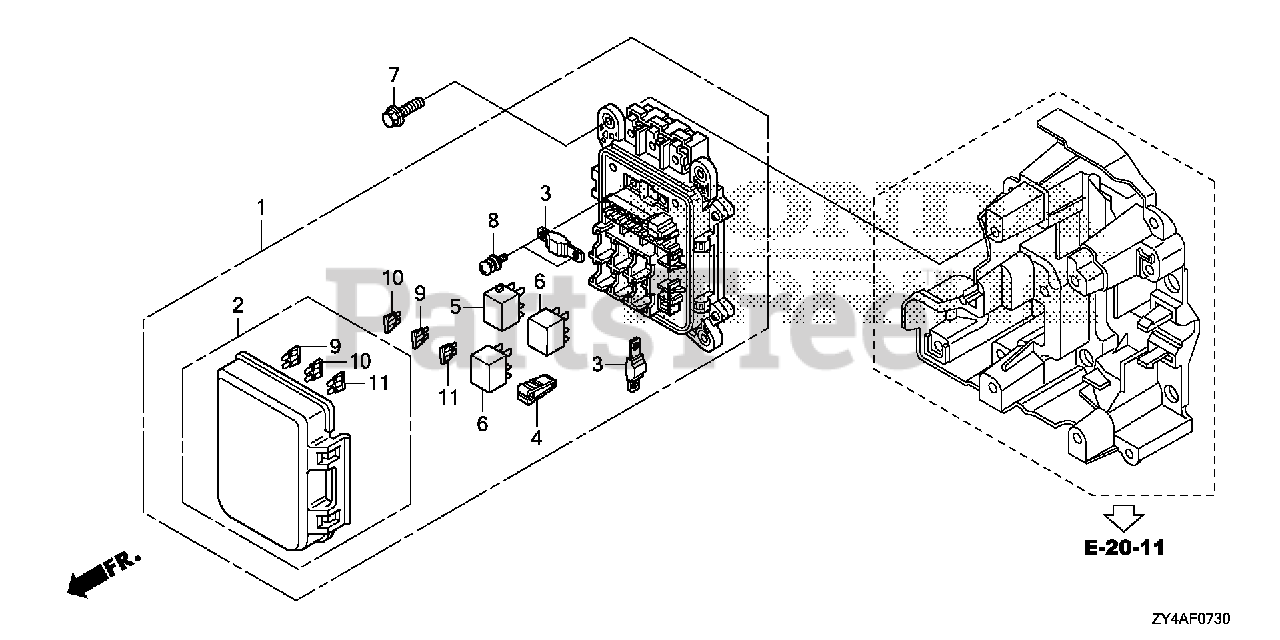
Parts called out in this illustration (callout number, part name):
1	BOX ASSY., JUNCTION
2	COVER, FUSE
3	FUSE, BLOCK (150A)
4	PULLER, MINI FUSE
5	RELAY ASSY., FUEL PUMP (DENSO)
6	RELAY ASSY., POWER (12V-20A) (MICRO ISO 4P)
7	BOLT, FLANGE (6X20)
8	SCREW-WASHER (5X15)
9	FUSE, MINI (10A)
10	FUSE, MINI (15A)
11	FUSE, MINI (30A)
